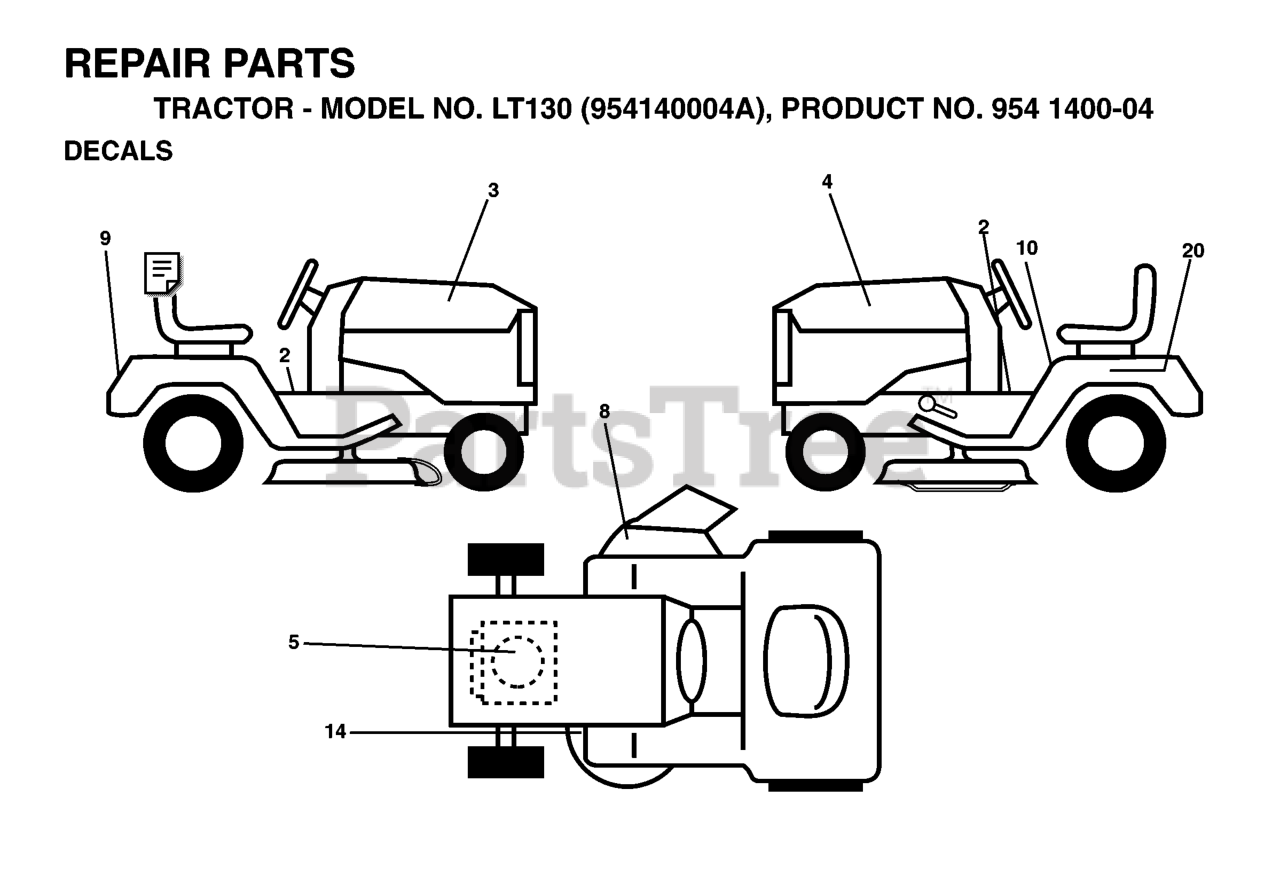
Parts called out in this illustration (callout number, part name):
2	DECAL FEND STLT OPER INST E/F
3	DECAL HOOD LH LT130
4	DECAL HOOD RH LT130
5	DECAL HP ENGINE
8	DECAL WARNING (ENGLISH/FRENCH)
9	DECAL FENDER HUSQ
10	DECAL FENDER DANGER
14	DECAL V-BELT SCHEMATIC
20	DECAL, BATTERY DANGER
